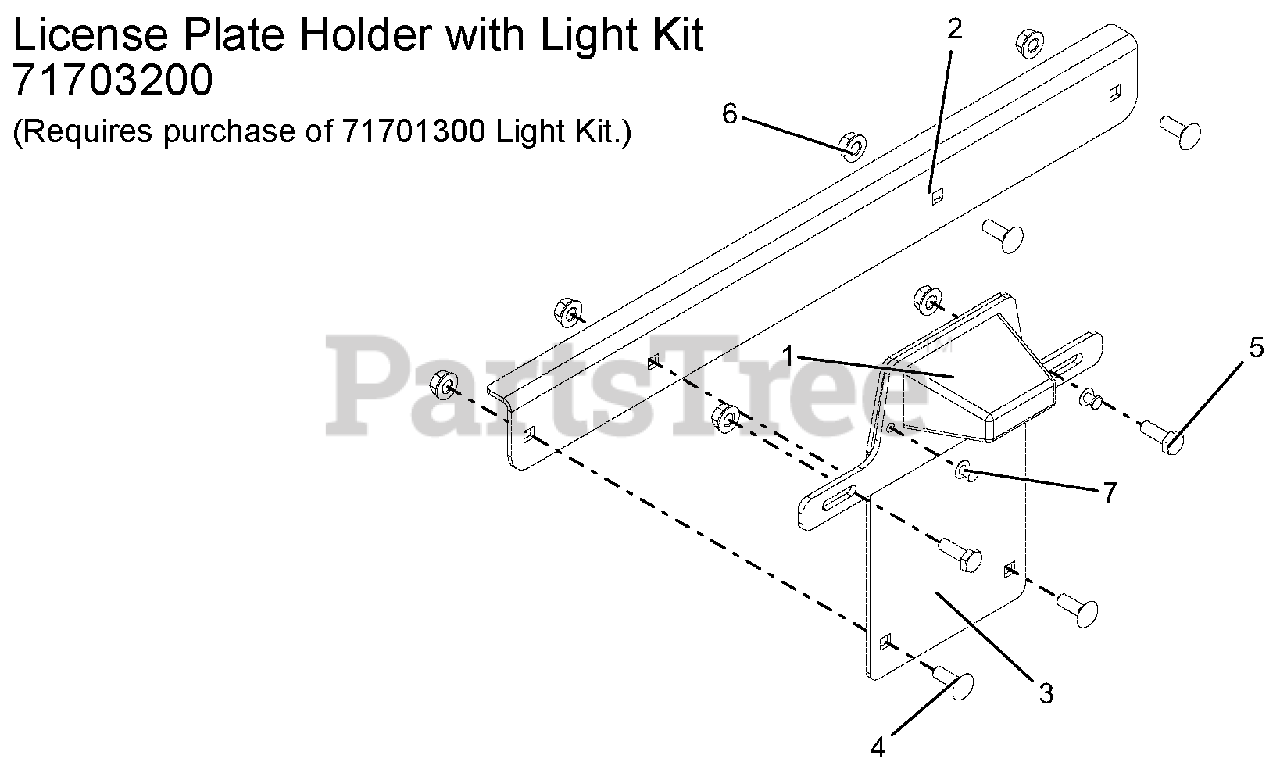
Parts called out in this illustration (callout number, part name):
1	LICENSE PLATE BRACKET W/ LIGHT
2	BRKT, SPLITTER LICENSE PLATE
3	SUPPORT, LICENSE PLATE BACK
4	@BLT-RDHDSQNK .25-20X.75 G5YZ
5	@BLT-HEX .25-20X.75 GR5 YWZC
6	@NUT-LK-TOP-FLG .25-20 YWZC
7	RVT-POP .187 YZ
